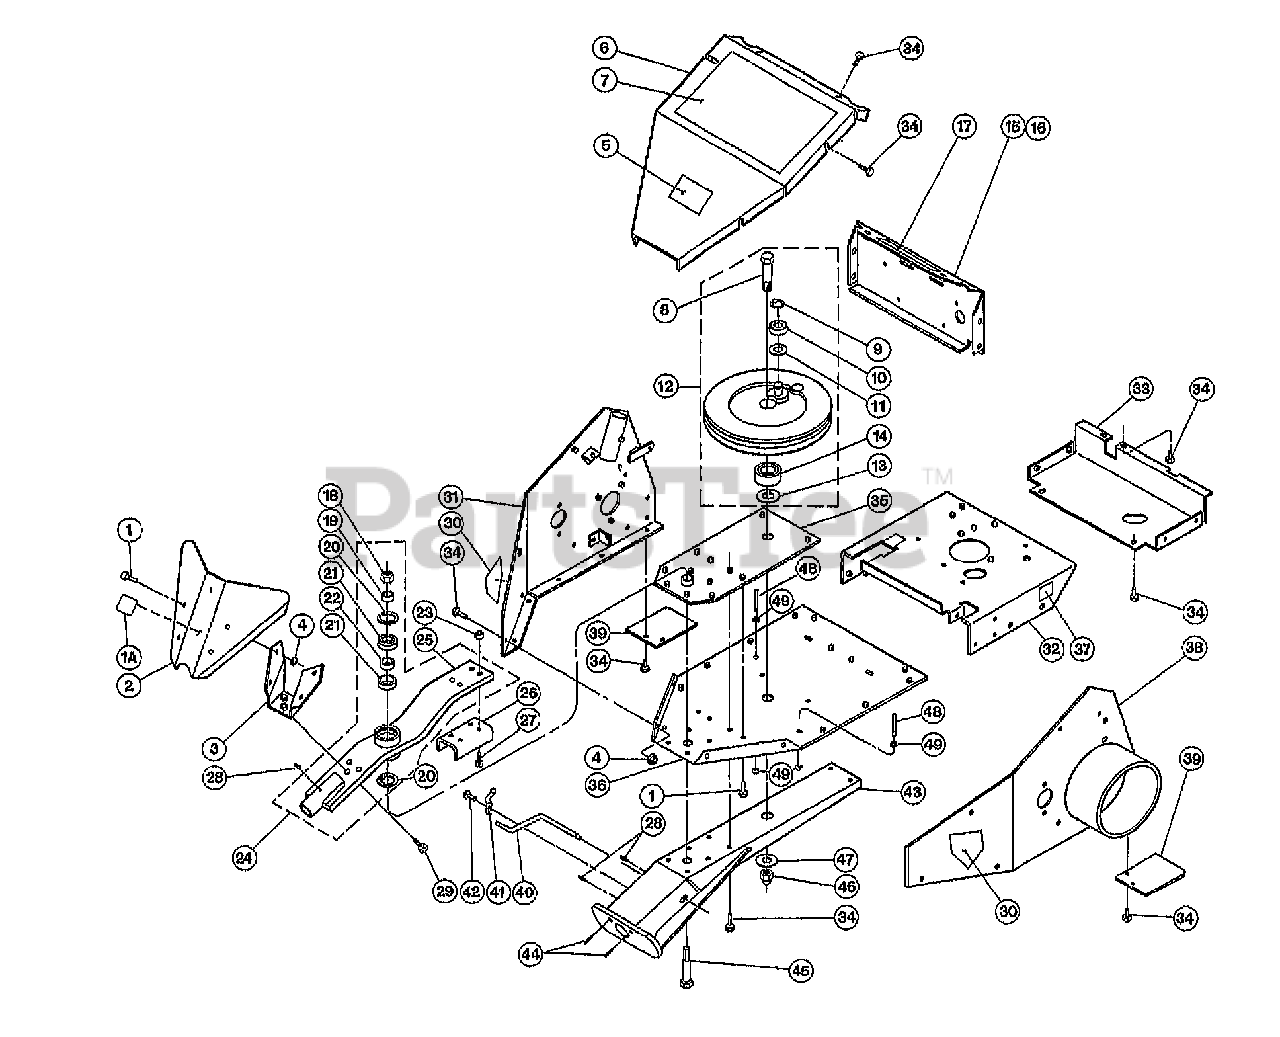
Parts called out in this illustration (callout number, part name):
1	SCR-HFLK 5/16-18X.62 G5ZP
1A	DECAL-DANGER WEED DEFLET
2	DEFLT-WEED W/DECALS (INCL. 1A - #40169)
3	DEFLECTOR-WEED PNT
4	NUT-HFLK 5/16-18 ZP
5	DECAL-DANGER (CUTTER BAR)
6	HOOD-PNT W/DECALS (INCL. 5 - #40160)
7	DECAL-LOGO TRAILBLAZER
8	BOLT-FLYWHEEL (SPECIAL)
9	RING-RETAIN EXT .669 ID
10	BEARING-ECCENTRIC
11	SHIM-1.125X.671X.048
12	ASSM-FLYWHEEL/BEARING
13	SHIM-1.375X.789X.048
15	HOOD-REAR PAINTED
16	HOOD-ELEC #40120PD
17	DECAL-SHRT CIR/CHRG INSTR
18	NUT-H/LK 5/8-11
19	WASHER-.5625
20	RING-RETAINING INT 1.575
21	BEARING-DRIVE ARM
22	SPACER-.6725X.96X.572
23	NUT-H/LK 5/16-18 NYLOCK
24	ASSM-DRIVE ARM
26	CHANNEL-DRIVEARM MACH
27	SCR-FH HXSKT 5/16-18X1.25
28	FITTING-GREASE STREIGHT
29	SCR-HFLK 5/16-18X1.00 ZP
30	DECAL-DANGER CUT FINGER
31	PLATE-RT FRAME, INCL. DECALS (INCL. 30)
32	ENGINE DECK
33	COVER-BELT CUTTERBAR RED
34	SCR-HFLK 5/16-18X.75 ZP
35	PLATE-#40146P
36	PLATE-FRAME BTM 40096P
37	DECAL-OIL DRAIN TUBE
38	PLATE-FRAME LT W/DEC (INCL. 30)
39	PLATE-WEED GUARD 40145P
40	PIN-CRANK
41	SPRING CLAMP-CRANK PIN
42	SCR-HW M10-32X.5 THRD ROLL
43	HOLDER-CUTTERBAR 40118P
44	PIN-SPIROL .375X 1.0
45	BOLT-DRIVE ARM
46	NUT-H/LK 3/4-10
47	WASHER-2.0X.75X.15 ZP
48	PIN-BELT GUIDE
49	NUT-TOP/LK 5/16-18 ZP
